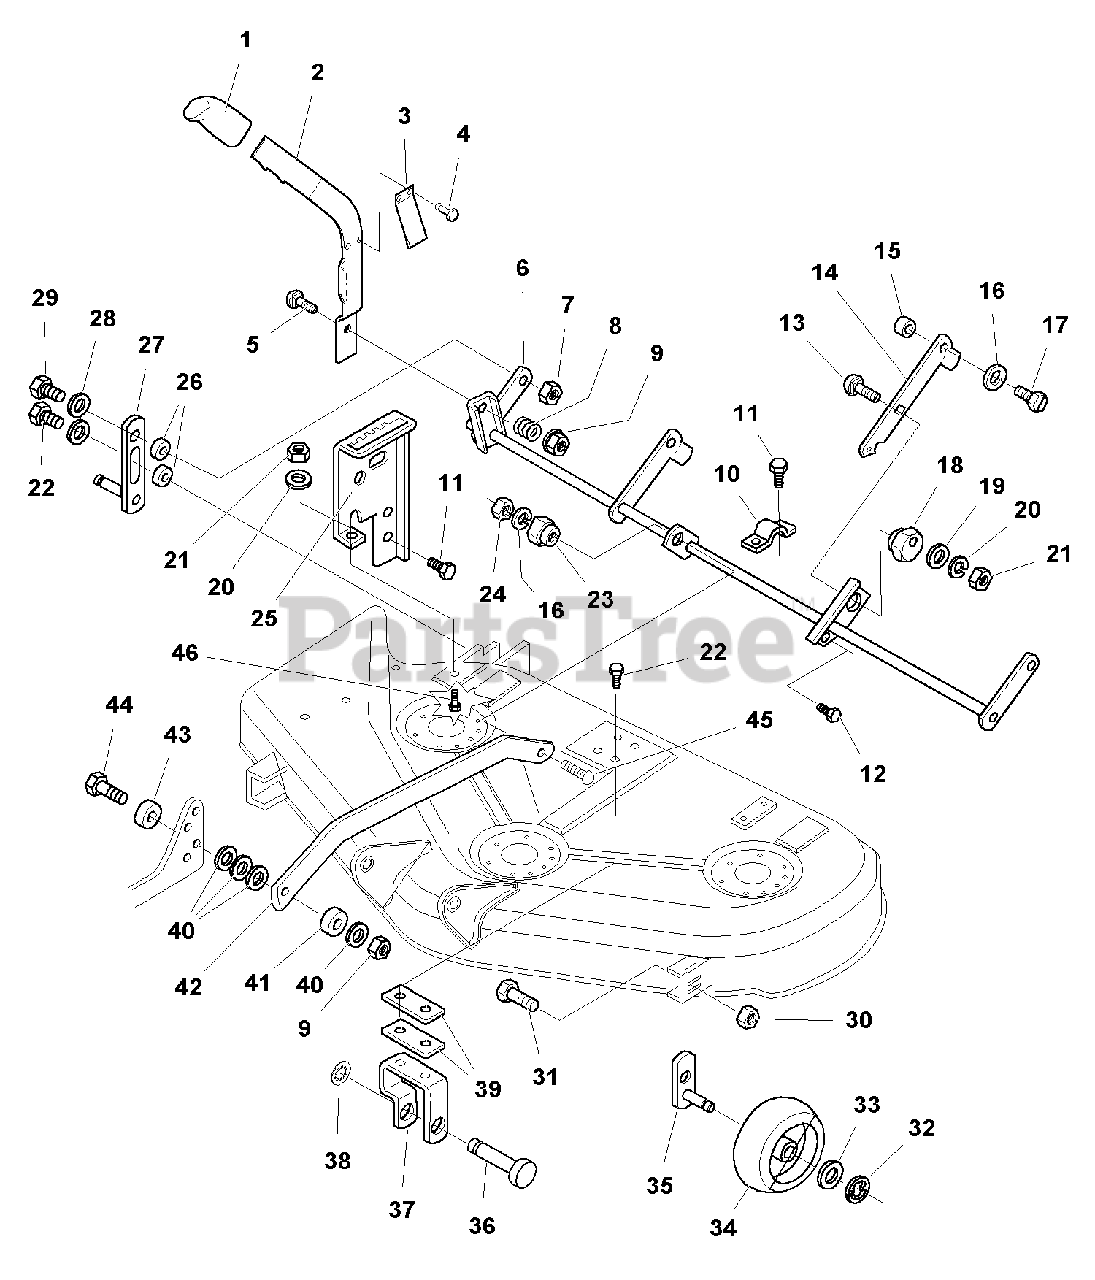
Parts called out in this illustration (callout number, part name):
2	ARM, Height Adjust (Includes Ref. Nos. 3 & 4)
5	CARRIAGE BOLT, 3/8-16 x 1-3/4
6	ROCKER ARM ASSEMBLY
7	NUT, Lock, 5/16-18
9	NUT, Flange Lock, 3/8
10	STRAP
11	CAPSCREW, Hex Head, Taptite, 5/16-18 x 3/4
12	CAPSCREW, Hex Head, Taptite, 5/16-18 x 7/8
13	CARRIAGE BOLT, 5/16-18 x 1-1/4
14	ARM ASSEMBLY, Rear Adjusting
15	SUPPORT, Mower
16	WASHER, Lock, 3/8
17	CAPSCREW, Hex Head, 3/8-16 x 1
19	WASHER
20	WASHER, Lock, 5/16
21	NUT, 5/16-18
22	CAPSCREW, Hex Head, Taptite, 5/16-18 x 1
23	NUT, Hex Adjusting, .99 DIA .687
24	NUT, Hex, 3/8
27	ARM ASSEMBLY
29	CAPSCREW, 5/16-18 x 1
30	NUT, Flanged 2-Way Lock, 1/4-20
31	CAPSCREW, Hex Head, 1/4-20 x 3/4
32	E-RING, 1/2
33	WASHER, 1/2
34	WHEEL, Gauge
35	ARM ASSEMBLY, Fixed
36	ROD, Mower Hitch
37	BRACKET, Gauge Wheel
38	NUT, Push, 1/2
39	STRAP
40	WASHER, Flat, 3/8
44	CAPSCREW, 3/8-16 x 1-1/4
45	CARRIAGE BOLT, 3/8-16 x 1-1/2
46	CAPSCREW, Hex Head, 5/16-18 x 3/4
